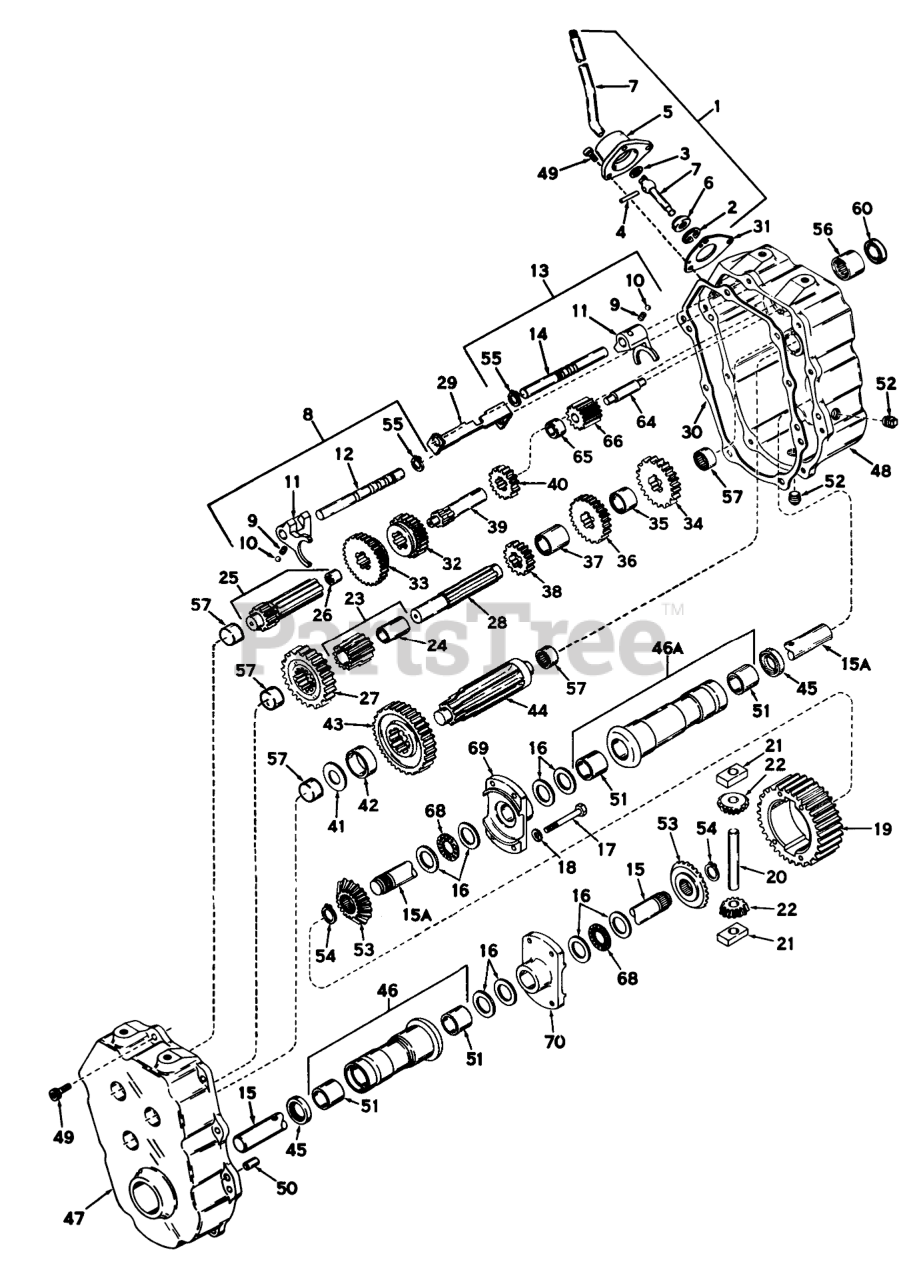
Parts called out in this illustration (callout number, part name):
1	Lever & Housing Assy., Shift (Incl. Nos. 2 thru 7)
2	Ring-Snap
3	"O" Ring
4	PIN-ROLL, SLOTTED
5	Housing, Shift lever
6	Keeper, Shift lever
7	Lever, Shift
8	Rod Assy., Shift (Incl. Nos. 9 thru 12)
9	Spring
10	Ball
11	Shift Fork
12	Rod, Shifter
13	Rod Assy., Shift (Incl. Nos. 9, 10, 11, 14, 55)
14	Rod, Shifter
15	Axle, L.H.
16	Axle, R.H.
17	Washer
18	SCREW-HH
19	WASHER-LOCK
20	Gear, Ring
21	Pin-Drive
22	Biock-Drive
23	Pinion-Bevel
24	Pinion & Bushing Assy. (Incl. No. 24)
25	Bushing
26	Shaft Bearing Assy., Shifter (Incl. No. 26)
27	Bearing
28	Gear-Spur
29	Shaft, Idler
30	Stop, Shifter
31	Gasket, Case to Cover
32	Shift Lever Housing Gasket
33	Gear, Shifting
34	Gear, Shifting
35	Gear, Spur (26 teeth)
36	Spacer
37	Gear, Spur (22 teeth)
38	Spacer
39	Gear, Spur (16 teeth)
40	Shaft, Input
41	Gear (10 teeth)
42	Washer
43	Spacer
44	Gear-Output
45	Shaft, Output
46	Seal, Oil
47	Housing & Bushing Assy., L.H. Axle (Incl. Nos. 51)
48	Housing & Bushing Assy., R.H. Axle (Incl. No. 51)
49	Cover Assy., Transaxle (Incl. No. 57)
50	Case Assy., Transaxle (Incl. Nos. 56 & 57)
51	SCREW-HSH
52	Dowel Pin
53	Bushing
54	PLUG-PIPE, SQH
55	Gear-Bevel
56	Ring-Snap
57	Ring-Snap
58	Bearing
59	Bearing
60	Oil Seal
61	Shaft, Reverse idler
62	Spacer, Reverse idler
63	Idler Reverse
64	Bearing-Thrust
65	Carrier, Differential
66	Carrier, Differential
